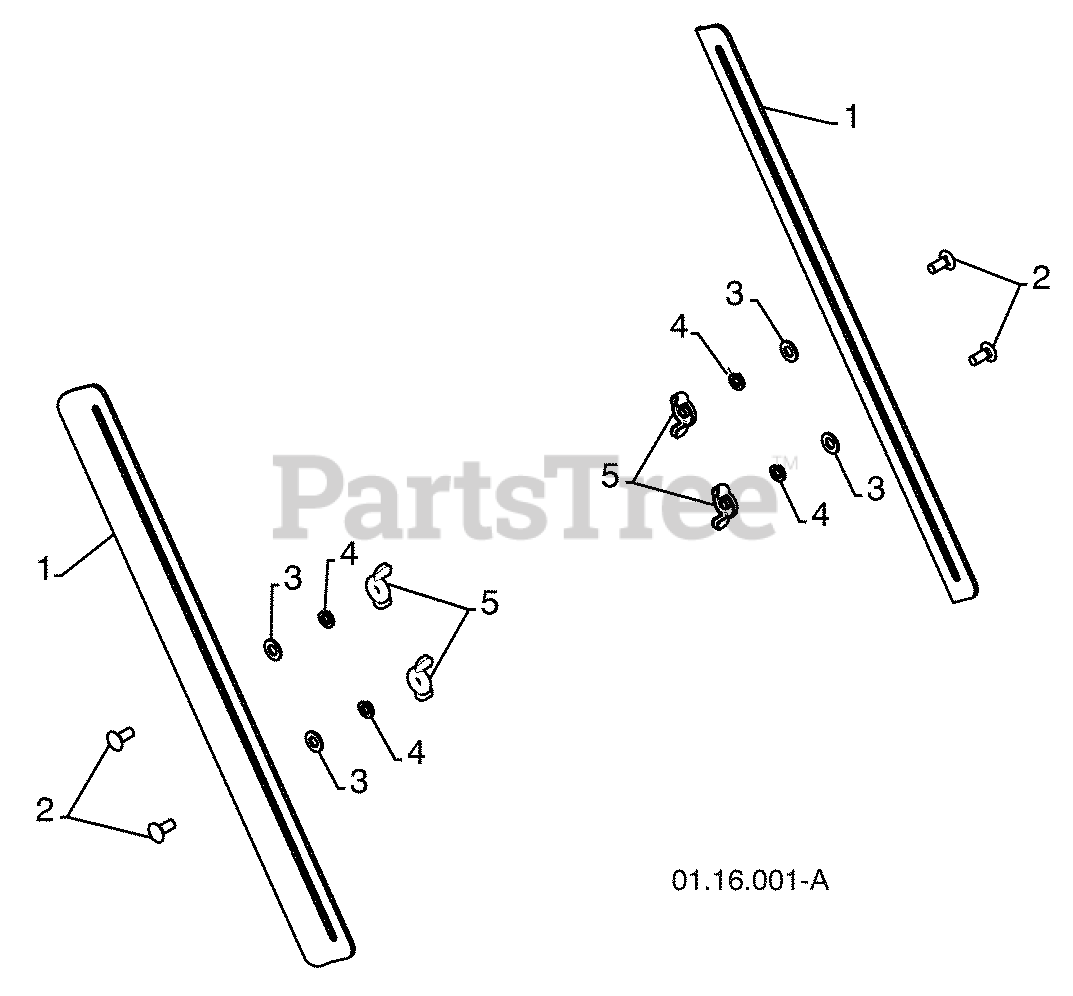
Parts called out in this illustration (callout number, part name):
1	DRIFT CUTTER BAR
2	BOLT
3	WASHER, NYLON FRICTION
4	WASHER.LOCK.HVY.HLCL.SPR.5/16
5	NUT WING PM
